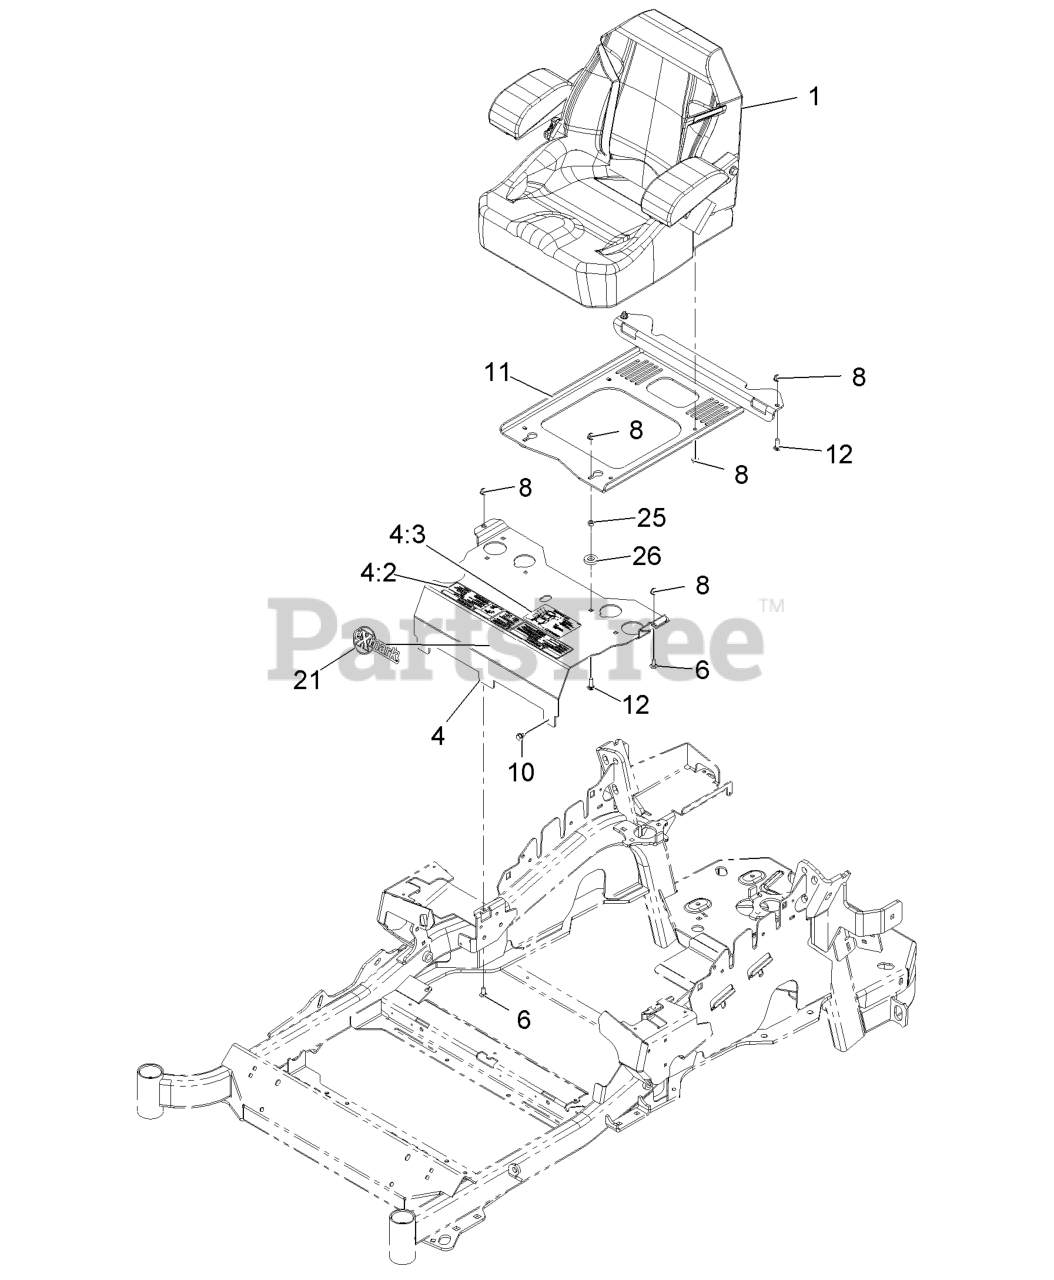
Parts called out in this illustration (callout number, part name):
4	MOUNT-SEAT
4:2	DECAL-CONSOLE
4:3	DECAL-SERVICE AID
6	SCREW-CARR
8	NUT-HF, NI
11	PLATE-SUPPORT, SEAT
12	SCREW-CARR
25	NUT-HEX
